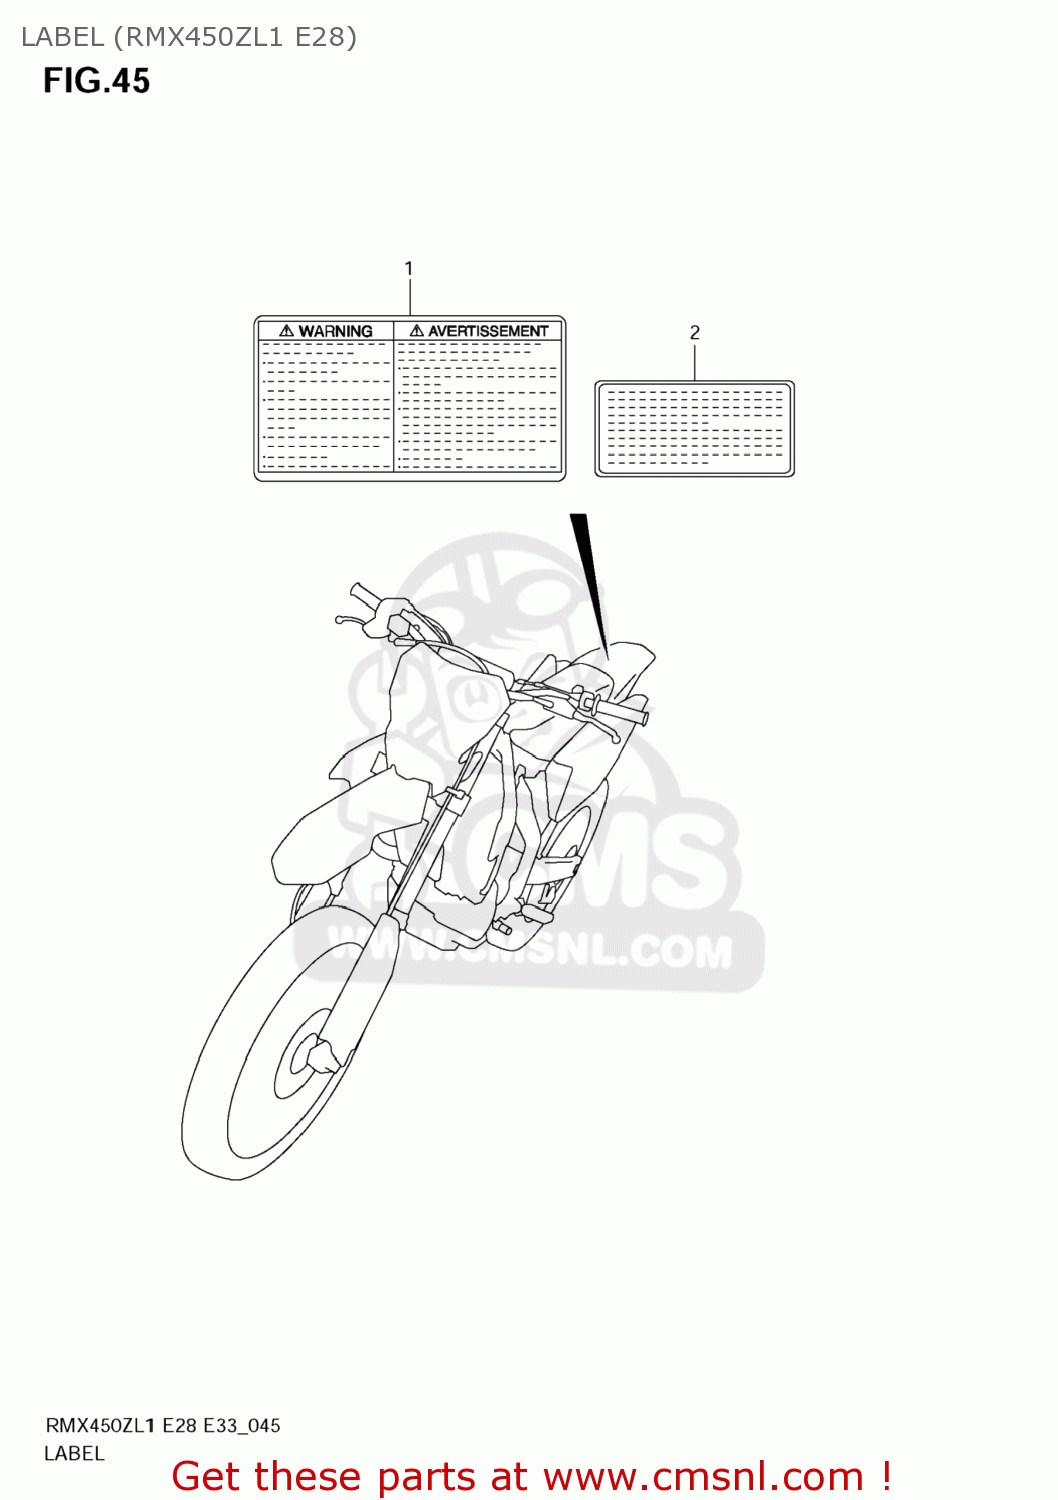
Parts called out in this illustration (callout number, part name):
1	LABEL,GENERAL WARNING
2	LABEL,FUEL INFORMATION
3	MANUAL,OWNER'S
